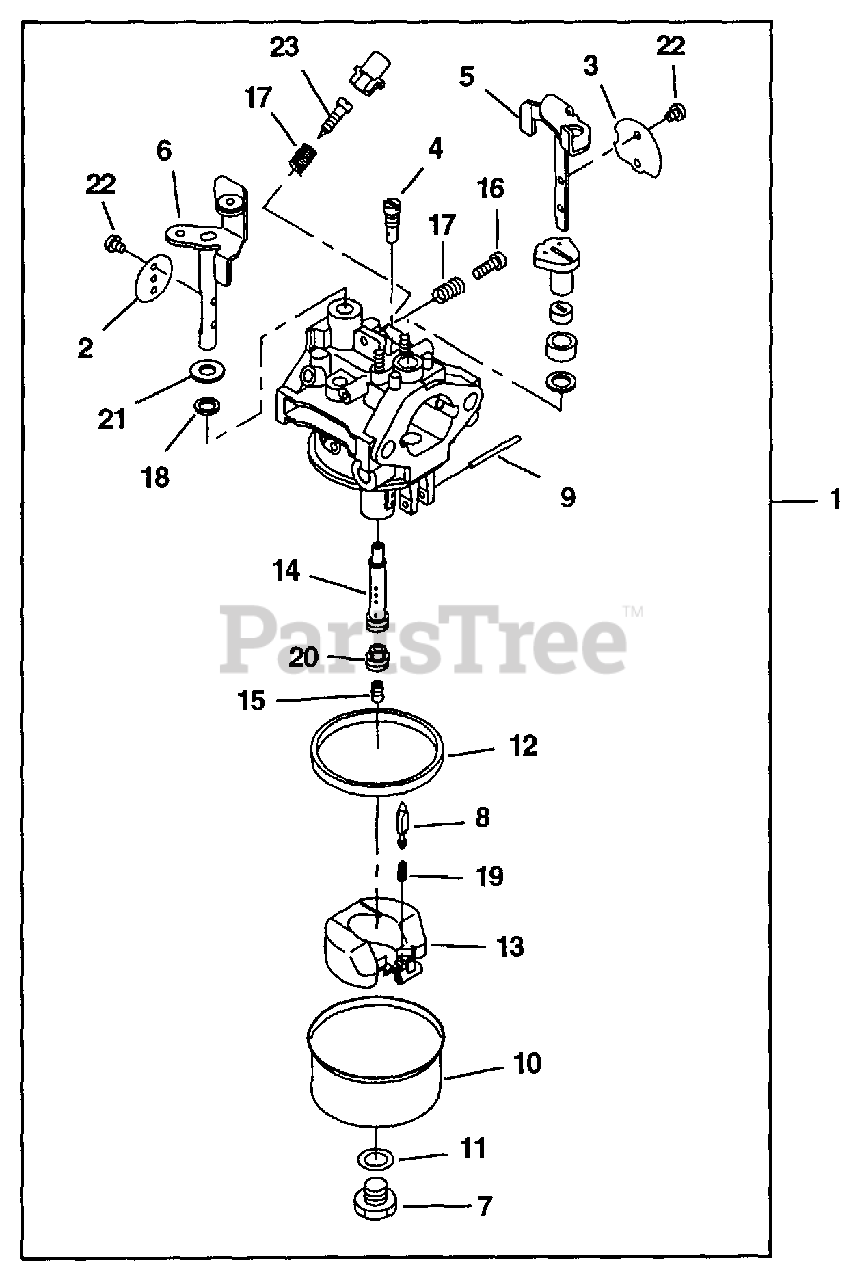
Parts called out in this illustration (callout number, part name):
1	Carburetor
2	Throttle valve
3	Choke valve
4	Pilot jet
5	Choke lever
6	Throttle shaft
7	Bolt
10	Float chamber body
12	Chamber packing
14	Main nozzle
15	Main jet
16	Adjusting screw
20	Guide holder
22	Screw M2.5 X 0.45 X 4L
23	Adjuster
